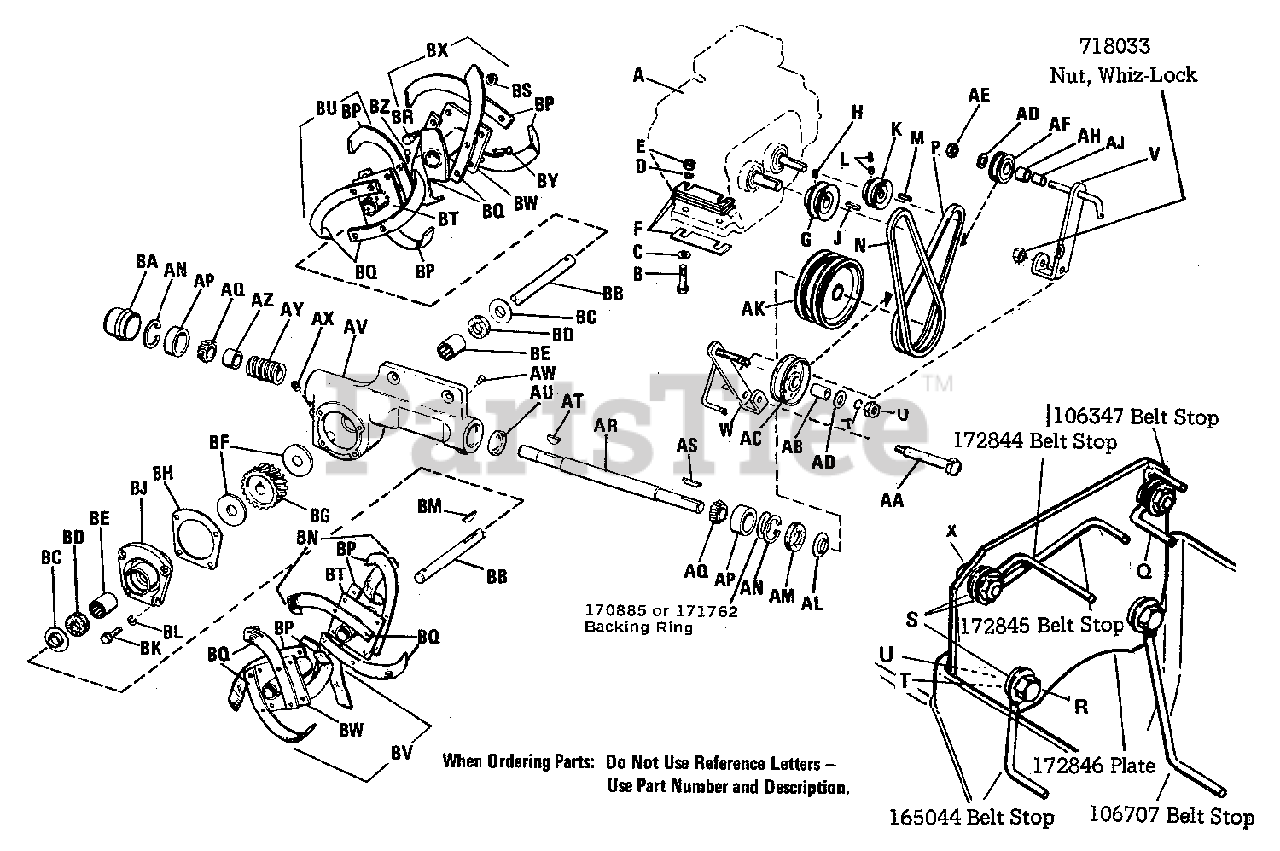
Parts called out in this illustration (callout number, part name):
A	ENGINE, Briggs & Stratton 5 H.P.
B	CAPSCREW, Hex, Head, 5/16-16 NC x 2" Lg.
C	WASHER, Plain, 5/16
D	WASHER, Lock, 5/16
E	NUT, Hex, Full, 5/16-18
G	PULLEY, Engine
H	SCREW, Set, 5/16-18 NC x 3/8" Lg.
K	PULLEY, Engine
L	SCREW, Set, 5/16-18 NC x 1/4" Lg.
N	BELT, "V" Reverse
P	BELT, "V" Forward
Q	BELT, Stop
R	CAPSCREW, Hex Head, 3/8"-18 NC x 1" Lg.
S	WASHER, Plain, 3/8"
T	WASHER, Lock, 3/8"
U	NUT, Hex, Full, 3/8"-16
V	LEVER ASSEMBLY, Idler
W	LEVER ASSEMBLY, Idler
X	CARRIAGE BOLT, 3/8"-16 x 1
AA	BOLT, Pivot
AC	PULLEY, Idler
AD	WASHER, Plain, 5/16"
AE	NUT, Lock, 3/8"-16 NC
AF	PULLEY, Idler Assembly, w/Bushing
AK	PULLEY, Driven
AN	RING, Snap
AP	CUP, Bearing
AQ	BEARING, Roller
AR	SHAFT, Worm
AV	HOUSING, Worm Drive
AX	PLUG, Pipe, 3/8"
AY	WORM, R.H.
BA	CUP
BB	SHAFT, Worm Gear
BE	BEARING, Needle
BF	WASHER, Thrust
BG	GEAR, Worm, R.H.
BK	CAPSCREW, Hex, Head, 1/4"-20 NC x 5/8" Lg.
BL	WASHER, Lock, 1/4"
BM	KEY, Woodruff
BN	INNER TINE ASSEMBLY, L.H.
BP	BLADE, Tine, L.H.
BQ	BLADE, Tine, R.H.
BR	CAPSCREW, Hex, 7/16"-20 x 1-1/4"
BS	NUT, Hex, Full, 7/16"-20
BT	PLATE ASSEMBLY, Inner Tine
BU	BLADE ASSEMBLY, R.H., Inner Tine
BV	EXTENSION, L.H., Tine Blade Assembly
BW	PLATE ASSEMBLY, Tine Extension
BX	EXTENSION, R.H., Tine Blade Assembly
BY	PIN
BZ	CLIP, Spring
